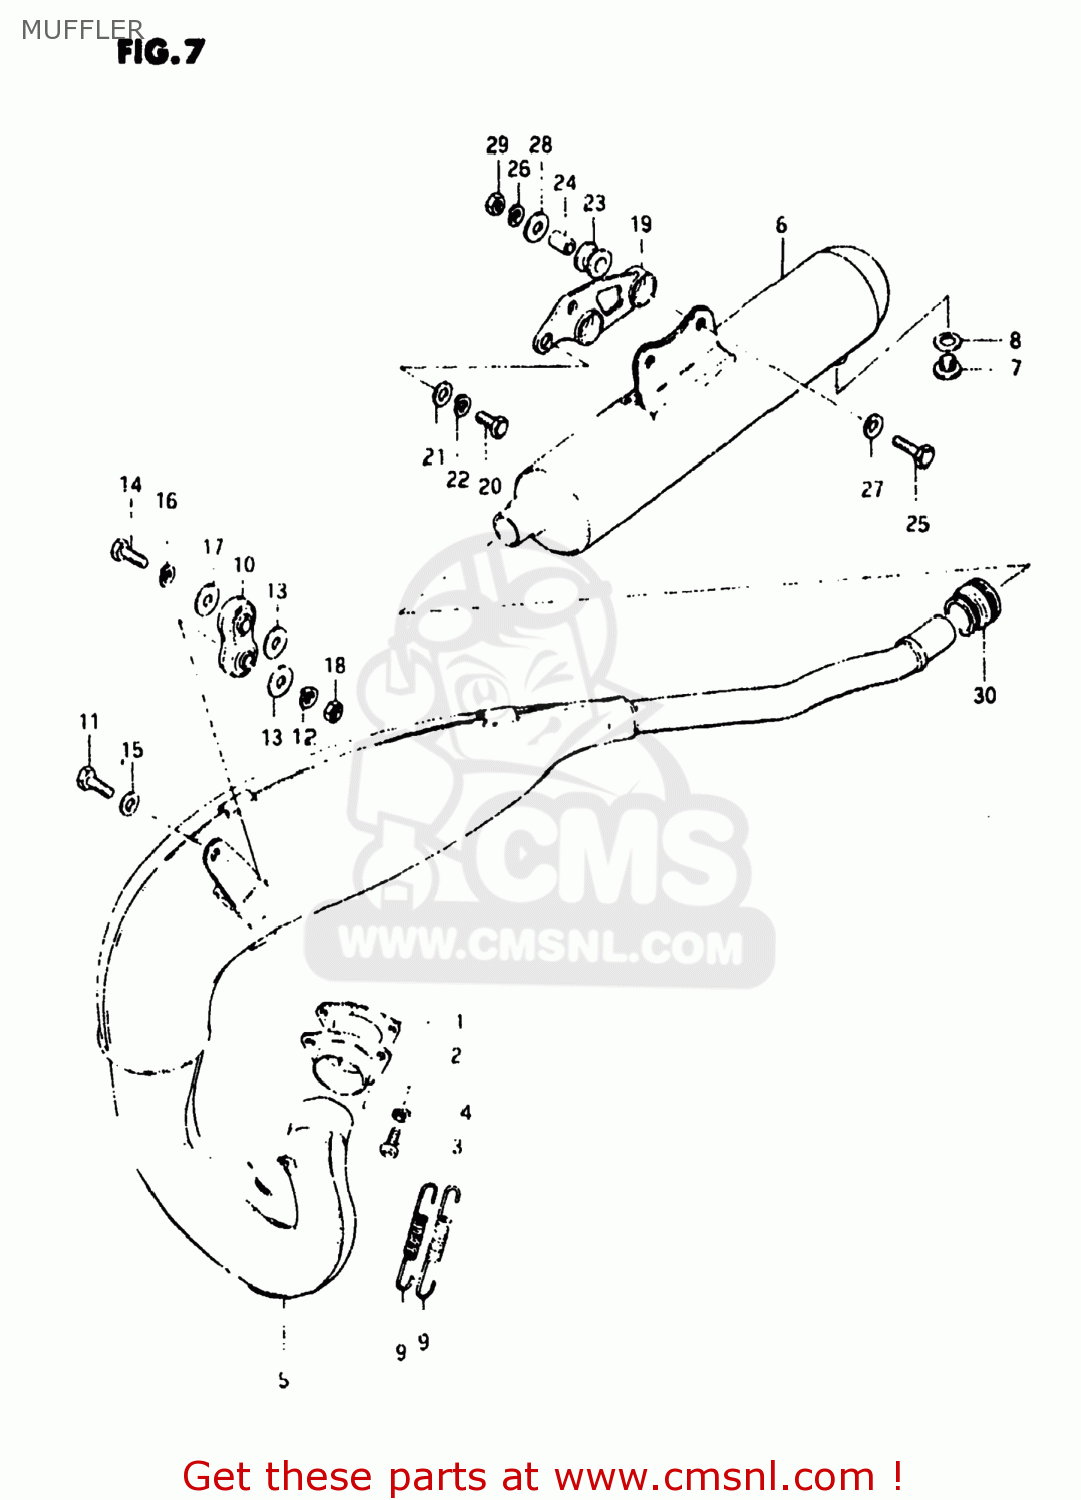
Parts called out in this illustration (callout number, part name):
1	GASKET,EXHAUST PIPE (MCA)
2	FLANGE,EXHAUST PIPE
3	SCREW
4	LOCK WASHER
5	MUFFLER ASSEMBLY,FIRST
6	MUFFLER ASSEMBLY
7	PLUG(12X9)
8	GASKET(12X16X2) (NAS)
9	SPRING
10	DAMPER,MUFFLER
11	BOLT
12	LOCK WASHER
13	WASHER
14	BOLT
15	WASHER
16	LOCK WASHER
17	WASHER
18	NUT
19	DAMPER,MUFFLER SUPPORT
20	BOLT
21	WASHER
22	LOCK WASHER
23	CUSHION
24	SPACER (8.2X12X17)
25	BOLT
26	LOCK WASHER
27	WASHER
28	WASHER (8.5X29X1.6)
29	NUT
30	CONNECTOR,MUFFLER
